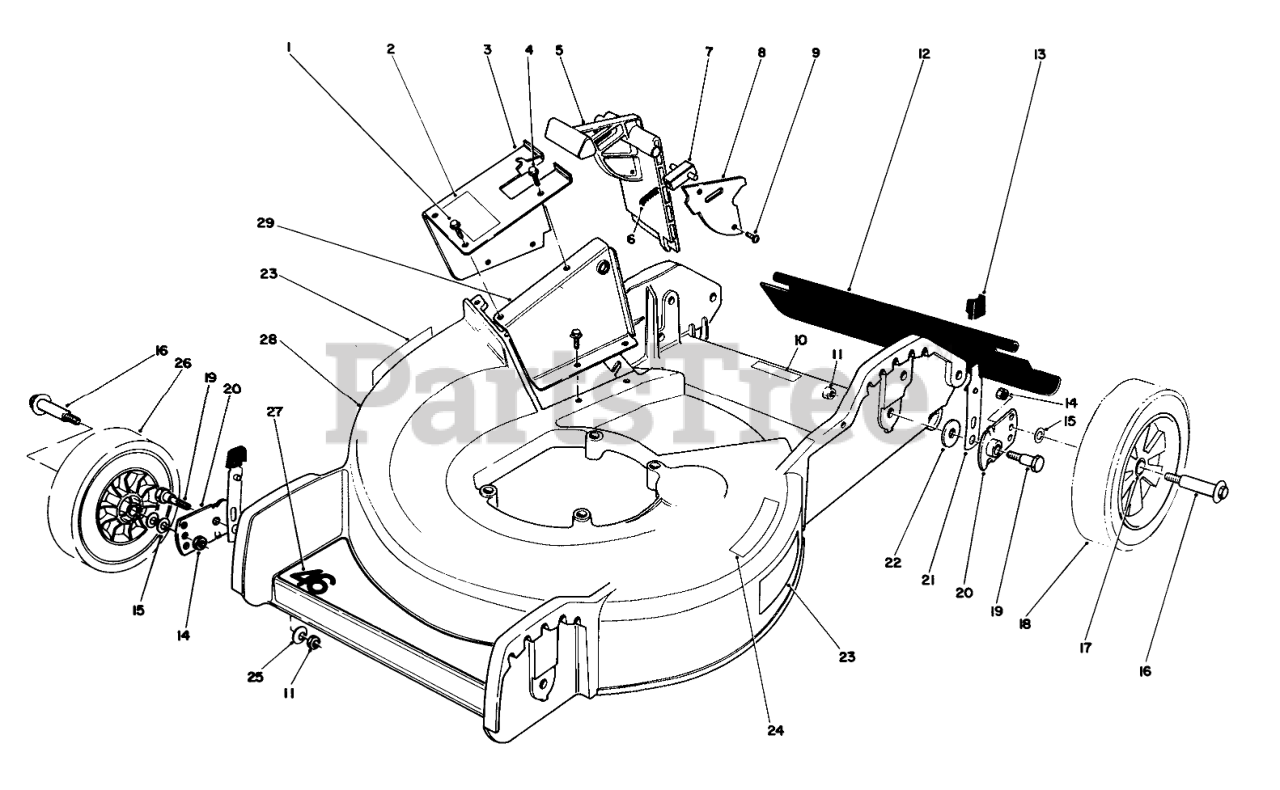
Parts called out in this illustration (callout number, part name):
1	SCREW
2	DECAL - DANGER
3	Tunnel-Outer
4	SCREW
5	Door Mulching
6	SPRING-COMPRESSION, LATCH
7	Door Latch
8	Cover Door
10	Decal
11	NUT-LOCK, NI
12	SHIELD - TRAILING
13	KNOB-ARM
14	Nut
15	WASHER
16	BOLT-WHEEL
17	BUSHING
18	Wheel & Tire Assembly (Incl. Ref. #17)
19	5/16-18 PIVOT SCREW
20	PIVOT ARM ASSY
21	SPRING ARM ASM
22	PIVOT WASHER
23	Decal Danger
24	DECAL - STEP PAD INT'L
25	WASHER-BELLEVILLE
26	Wheel & Tire Assembly (Inc. Ref. #17)
27	DECAL - DECK
28	HSG & CARTON
29	Tunnel-Inner
